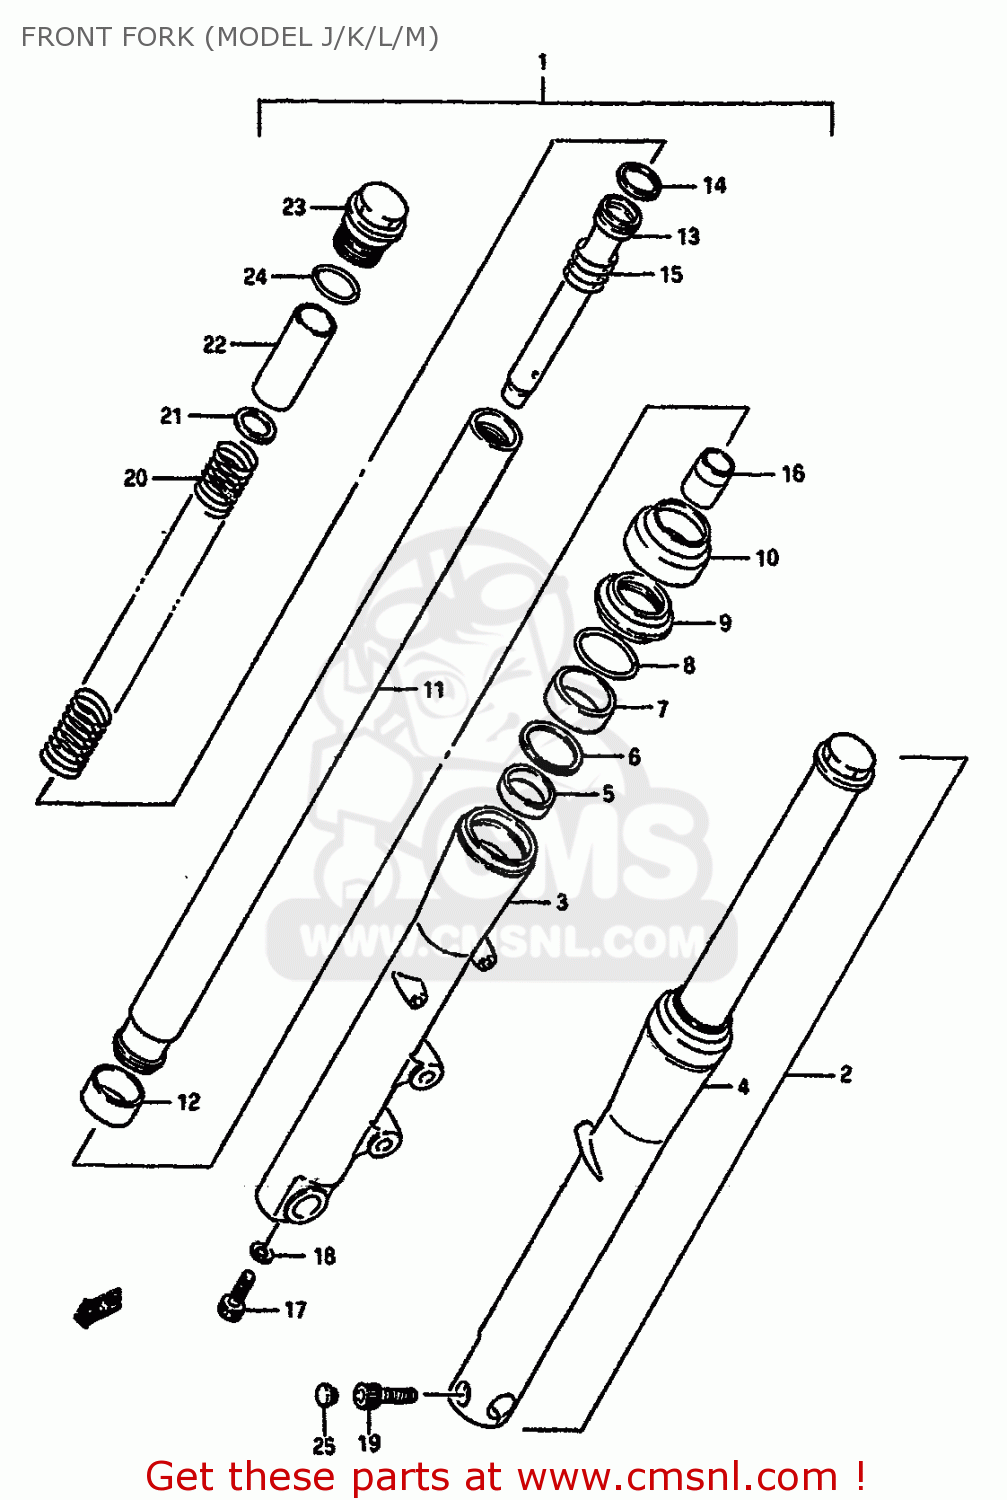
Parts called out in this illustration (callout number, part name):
1	DAMPER ASSEMBLY,RIGHT
2	DAMPER ASSEMBLY,LEFT
3	TUBE,OUTER RH
4	TUBE,OUTER LH
5	BUSHING,GUIDE
6	SPACER,SEAL
7	OIL SEAL,FRONT FORK
8	CUSHION,HEADLAMP BRACKET
9	BOOT
10	BAND,FRONT FORK COVER
11	TUBE,FORK,INNER
12	BUSHING,SLIDE
13	PIPE,SEAT
14	RING,PISTON
15	SPRING,REBOUND
16	PIECE,OIL LOCK
17	BOLT(8X27)
18	GASKET (NAS)
19	BOLT, FRONT RH
20	SPRING
21	WASHER,SPRING
22	COLLAR,SPRING
23	BOLT,FORK
24	O RING
25	CAP(OD:14.5)
